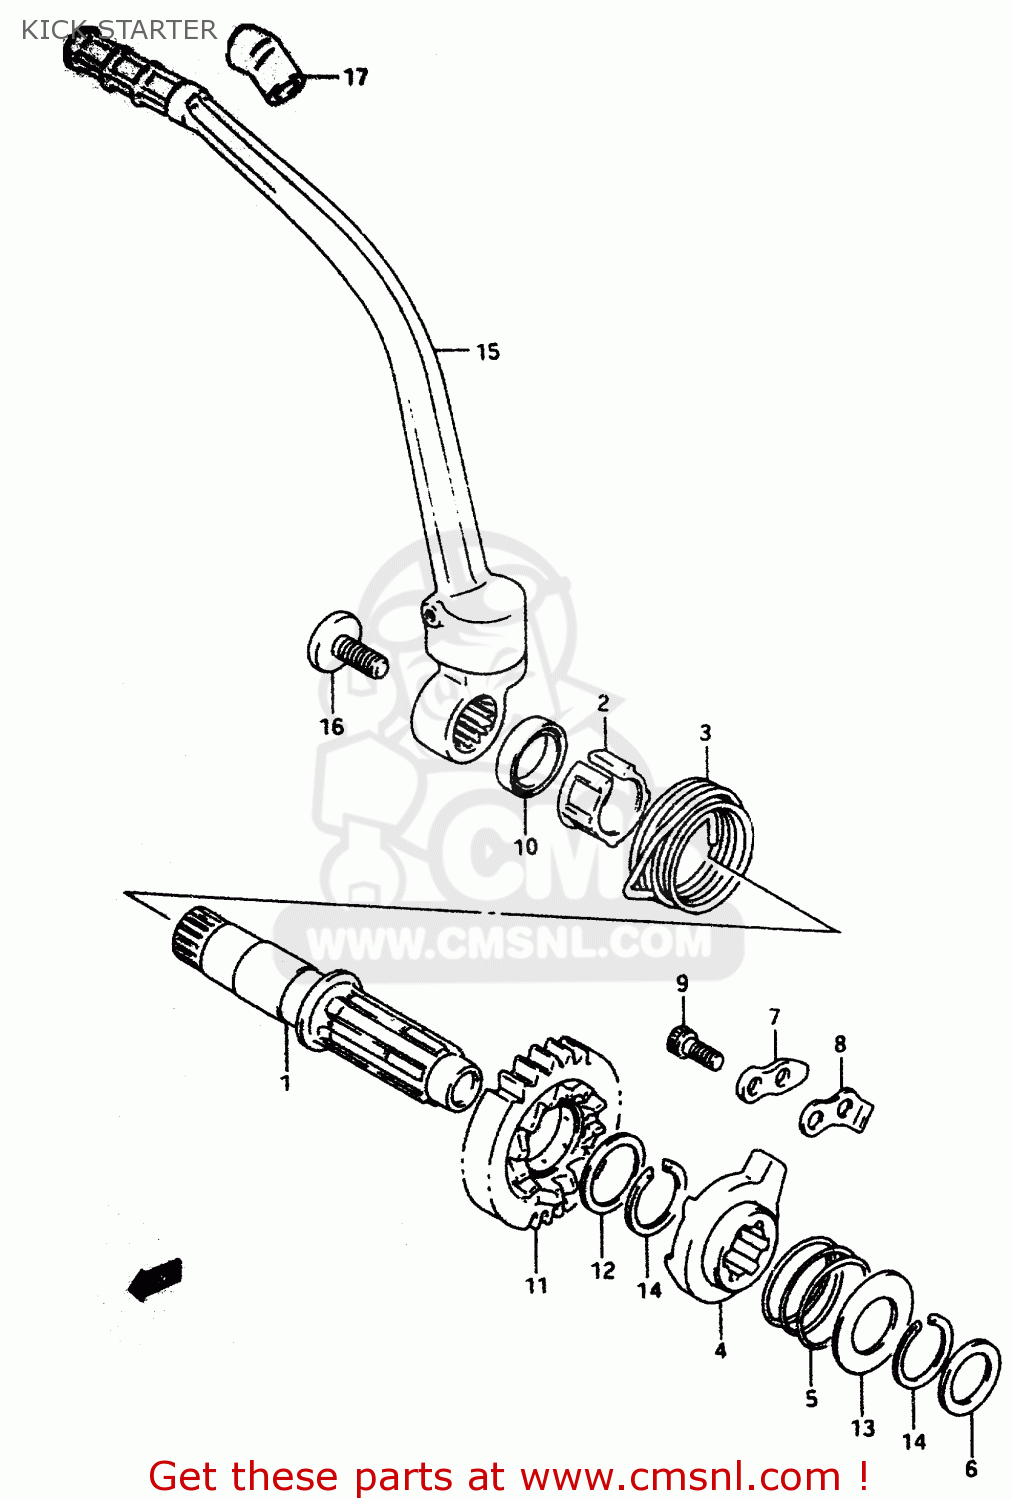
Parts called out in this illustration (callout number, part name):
1	SHAFT,KICK STARTER
2	GUIDE,KICK STARTER SFT SPRING
3	SPRING
4	STARTER,KICK
5	SPRING
6	SHIM(17X26X1)
7	GUIDE,KICK STARTER
8	STOPPER,KICK STARTER
9	BOLT,KICK START STOPPER
10	SEAL,OIL(20X27X6)
11	GEAR,KICK STARTER(NT:23)
12	SHIM(22X28X1)
13	SHIM(22X36X1)
14	CIRCLIP
15	LEVER ASSY,KICK STARTER
16	COVER,KICK STARTER LEVER
17	BOLT(8X14)
